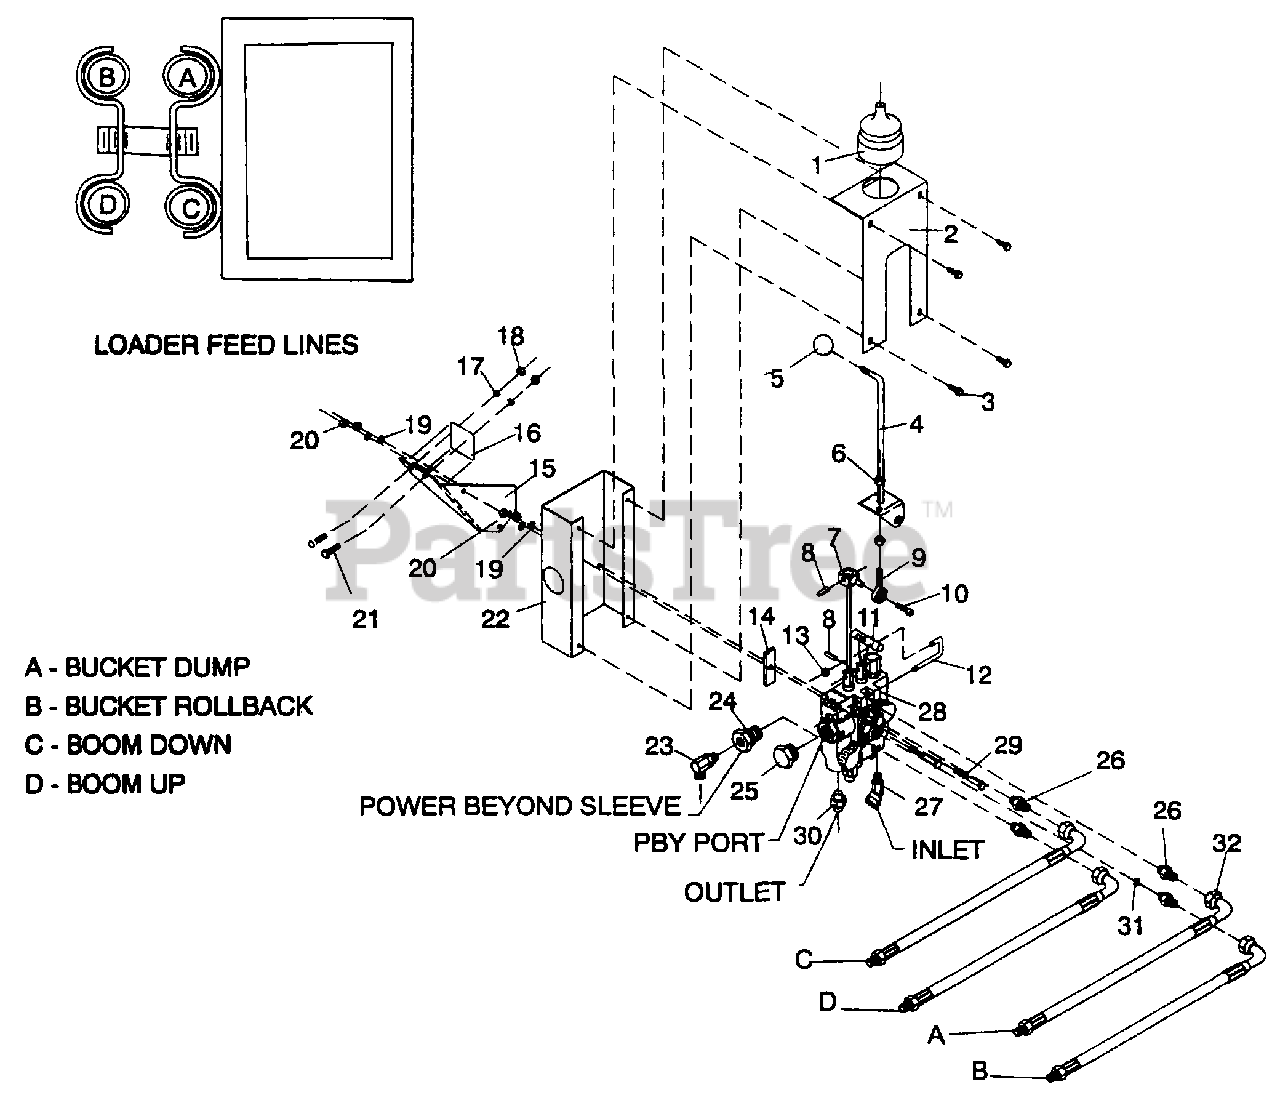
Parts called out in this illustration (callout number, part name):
1	Rubber boot
2	End cover
3	1/4 NC x 3/4 Self-tap screw
6	5/16 NF Hex nut
7	Pivot block
8	1/4 x 7/8 Roll pin
9	Rod end ball joint
10	1/4 x 1 Socket head cap screw
12	U-Bolt
13	1/4 NC Self-lock hex nut
15	Valve mounting bracket
16	Control valve decal
17	3/8 Lockwasher
18	3/8 Hex nut
19	1/4 Lockwasher
20	1/4 NC Hex nut
21	3/8 x 1 Carriage Bolt
22	Valve cover
23	Elbow 9/16 ORBM x 1/2 NPSM 90°.
24	Power beyond sleeve
25	Cap plug (open center hyd. only)
26	9/16 ORM x 9/16 JICM Adapter
27	Elbow 9/16 ORBM x 1/2 NPSM 45°.
28	Model 1006 Valve
29	1/4 NC x 2-1/2 Cap screw GR5
30	9/16 ORBM x 1/2 NPSM Adapter
31	Plate orifice
32	18" Hose
